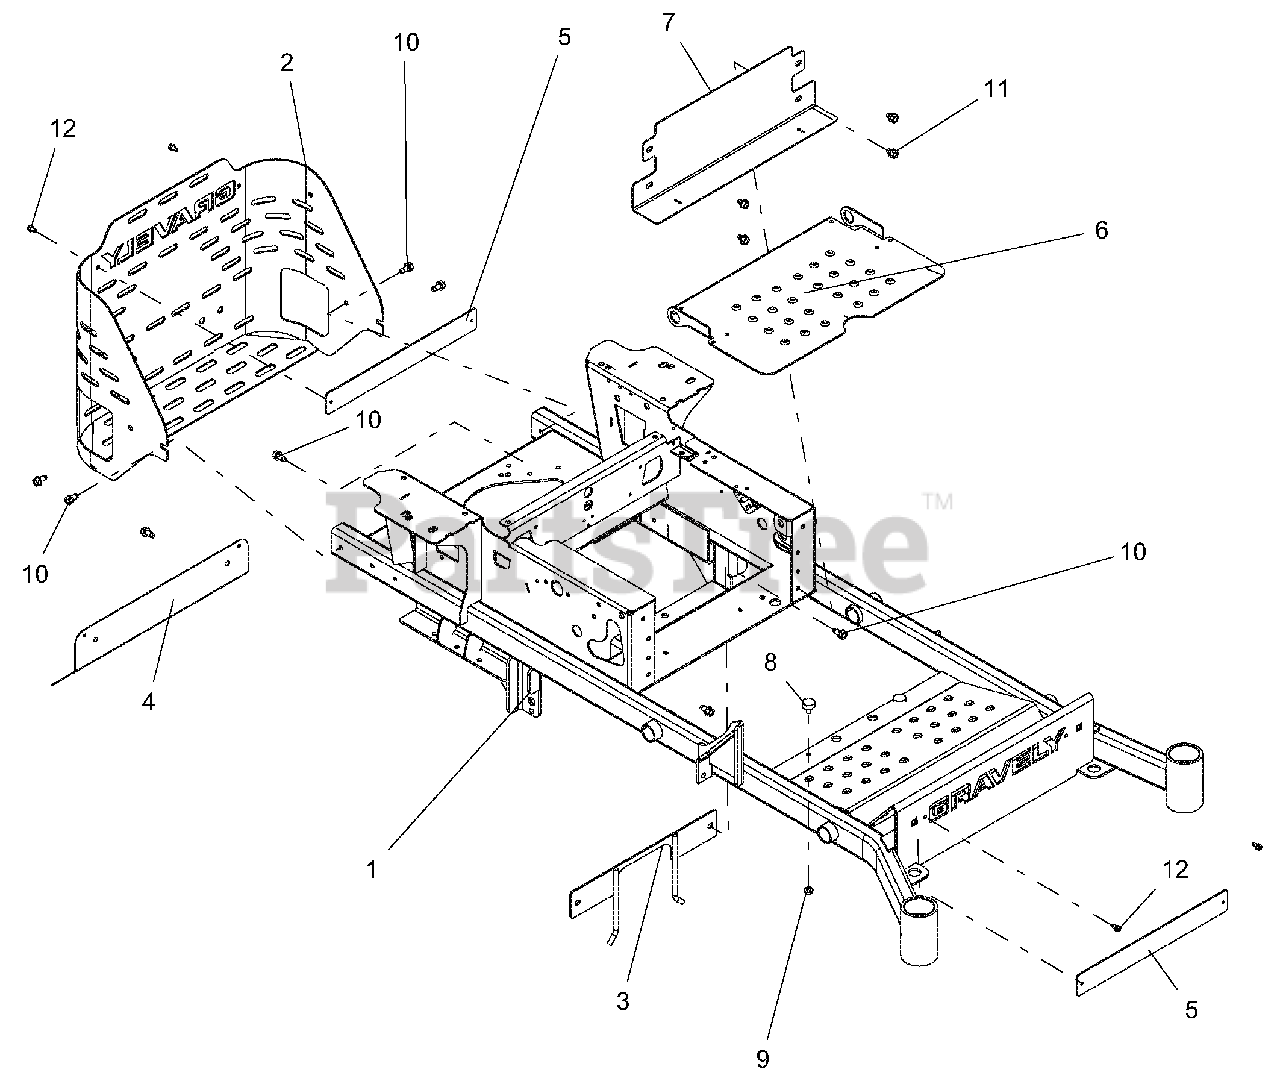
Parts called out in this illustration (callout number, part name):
1	48-52" MAIN FRAME W/SAFETY DECALS
2	REAR BUMPER W/SAFETY DECALS
3	WLDMT, PTO BELT FINGER-BLACK
4	SHIELD, MUFFLER HEAT
5	PLATE, BUMPER 2.00 x 16.50 - BLK
6	FOOT, PLATE W/SAFETY DECALS
7	PLATE, PT/PT100 KICK-RED
8	BUMPER, RUBBER
9	@NUT-SPNLK-FLG .312-18 YWZC
10	SCR-TAP .38-16X.75 HWH TR YWZ
11	SCR-TAP .38-16X.50 HWH TR YWZ
12	SCR-TAP .25-20X.50 HWH TR YWZ
